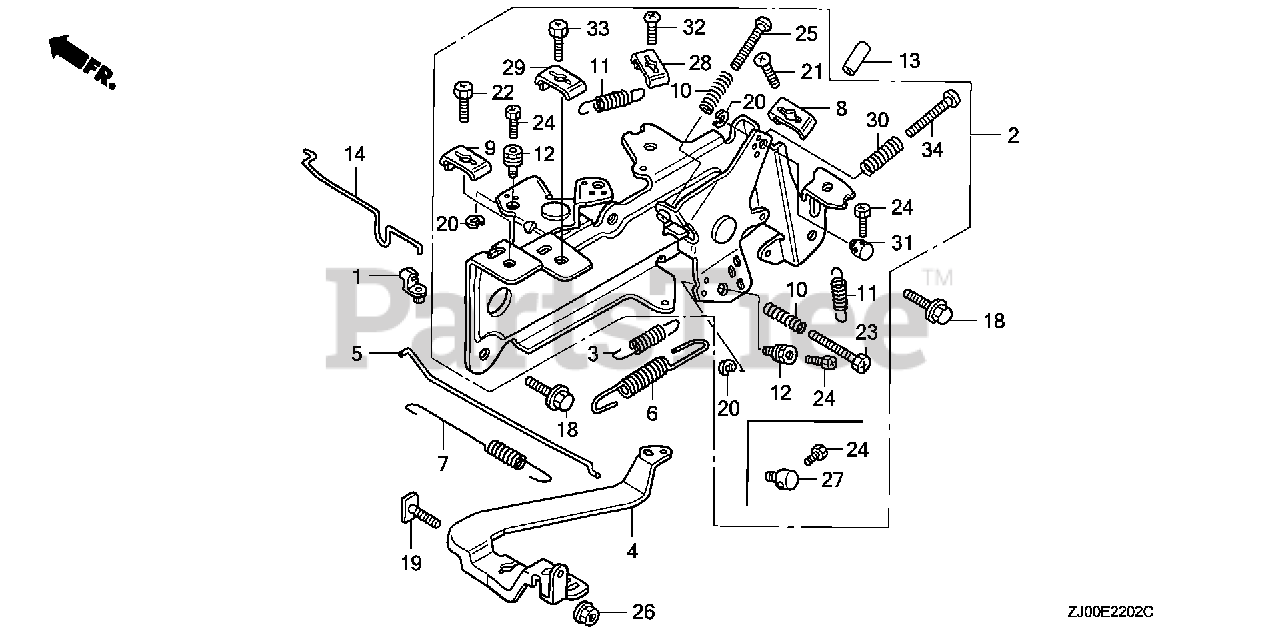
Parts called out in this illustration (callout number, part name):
1	JOINT, ROD
2	CONTROL ASSY.
3	SPRING, STARTER
4	ARM, GOVERNOR
5	ROD, GOVERNOR
6	SPRING, GOVERNOR
7	SPRING, THROTTLE RETURN
8	HOLDER, CABLE
9	HOLDER, CABLE
10	SPRING, CONTROL ADJUSTING
11	SPRING, CABLE RETURN
14	ROD, CHOKE CONTROL
18	BOLT, FLANGE (6X14) (CT200)
19	BOLT, GOVERNOR ARM
21	BOLT, RECESSED (5X16)
22	BOLT, RECESSED (5X16)
23	BOLT, RECESSED (5X25)
25	SCREW, PAN (5X25)
26	NUT, FLANGE (6MM)
28	HOLDER, CABLE
29	HOLDER, CABLE
32	BOLT, RECESSED (5X16)
33	BOLT, RECESSED (5X16)
